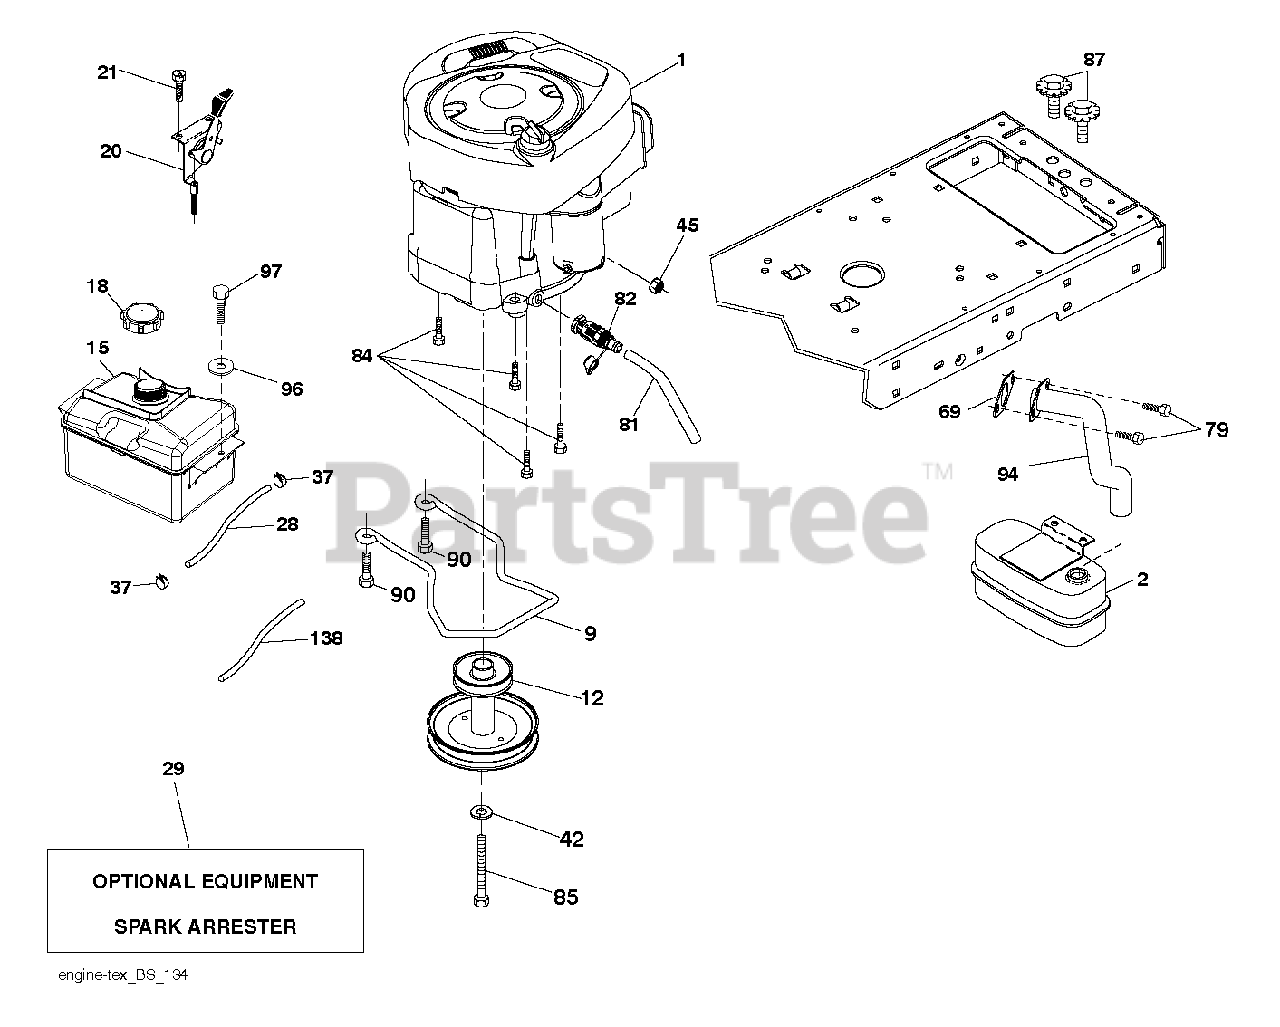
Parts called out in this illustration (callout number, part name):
2	Muffler Assembly, Single
9	KEEPER.BELT.ENG.4.25"2.BLT.431
12	ENGINE.PULLEY
15	Front Tank Assembly, 2.5 Gallon
18	CAP.FUEL.2 WAY VENT
20	CONTROL.TH/CK.C.
21	SCREW.#10 X 0.750.BOS
28	LINE.FUEL.20"FRONT.EMI
29	KIT.SPARK ARRESTOR 794945 B&S
37	HOSE CLAMP
42	WASHER 7/16 LOCK
45	NUT
69	REPL BY 532 27 22-93
79	SCREW.SOCKET HD.5/16-1
81	TUBE, DRAIN OIL ASM.
82	VALUE.OIL.DRAIN
84	SCREW.3/8-16
85	BOLT.HEX.7/16-20X4.GR5.1.5BLUE
87	BOLT, 5/16-18 X 1 3/4
90	SCREW 3/8-16X1
94	EXHAUST.TUBE.B&S.28/31
97	SCREW HEXWSHR 1/4-20X3/4
138	RP PURGE LINE
